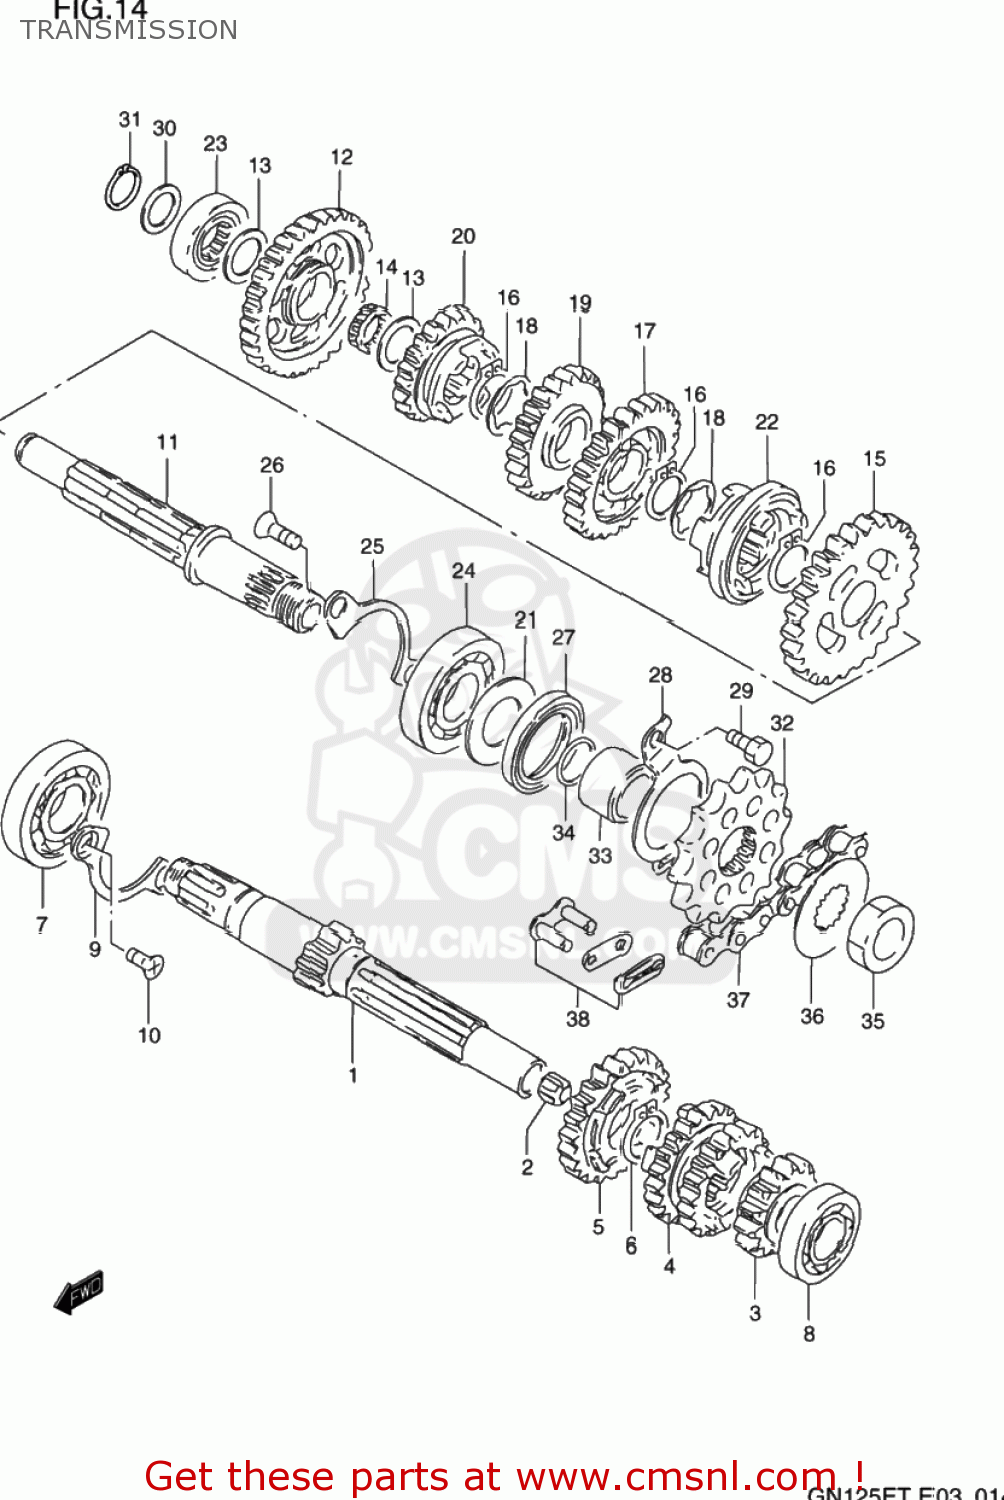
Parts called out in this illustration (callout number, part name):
1	SHAFT,COUNTER
2	BUSH
3	GEAR,SECOND DRIVE
4	GEAR,THIRD & FOURTH DRIVE,N
5	GEAR,FIFTH DRIVE
6	CIRCLIP
7	BEARING
8	BEARING
9	RETAINER,DRIVE SHAFT BEARING
10	SCREW
11	SHAFT,DRIVE
12	GEAR,FIRST DRIVEN
13	WASHER
14	BEARING(15X19X7.8)
15	GEAR,SECOND DRIVEN
16	CIRCLIP
17	GEAR,THIRD DRIVEN
18	WASHER,LOCK
19	GEAR,FOURTH DRIVEN
20	GEAR,FIFTH DRIVEN
21	WASHER,OIL SEALING
22	WHEEL,SLIDING DOG
23	BEARING(15X33X12)
24	BEARING
25	RETAINER,DRIVE SHAFT BEARING
26	SCREW
27	SEAL,OIL(27X40X6)
28	PLATE,DRIVESHAFT OIL
29	BOLT
30	WASHER
31	CIRCLIP
32	SPROCKET,ENGINE
33	SPACER
34	O RING(D:2.4,ID:19)
35	NUT
36	WASHER,LOCK
37	CHAIN ASSEMBLY,DRIVE
38	JOINT(RK)
